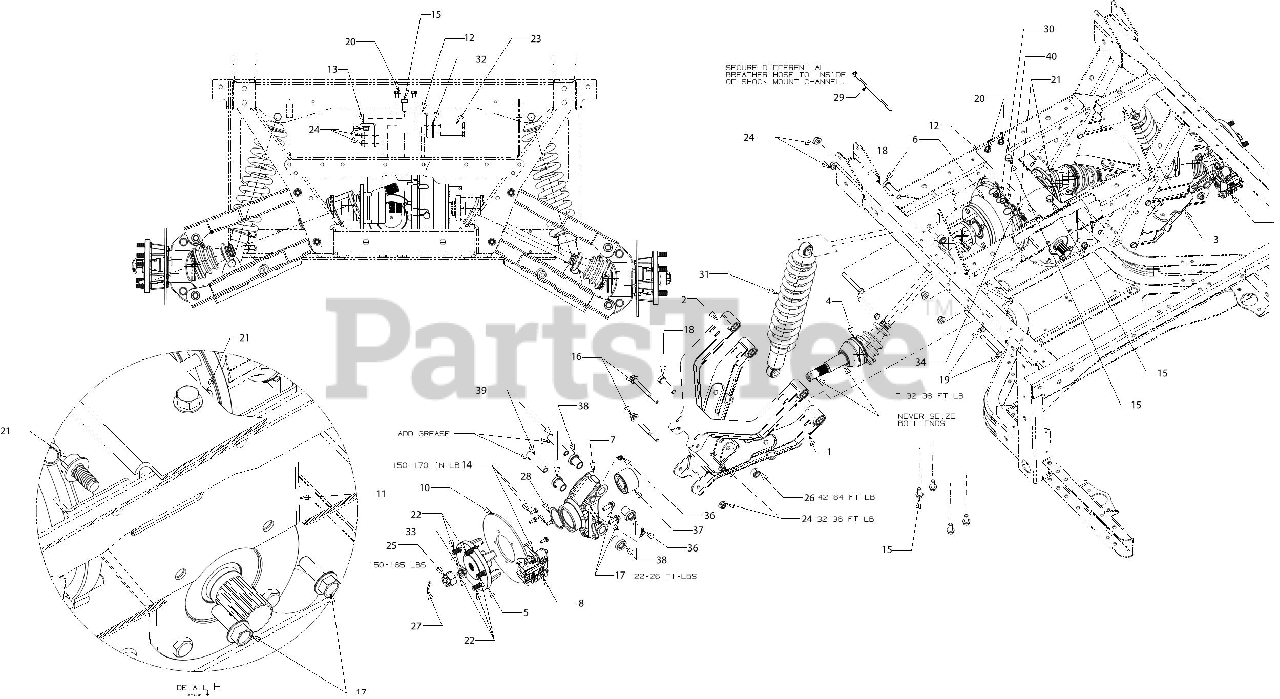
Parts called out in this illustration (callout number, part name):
1	LOWER CONTROL ASSEMBLY
2	UPPER CONTROL ASSEMBLY
3	LOWER CONTROL ASSEMBLY
4	CV JOINT AXLE:ASSEMBLY
5	WHEEL HUB ASSEMBLY
6	UV REAR DRIVE KIT
7	4X4 REAR HOUSING
8	FRONT BRAKE CALIPER ASSEMBLY (RH)
9	FRONT BRAKE CALIPER ASSEMBLY (LH)
10	BRAKE DISC 8.00 x .188
11	DIFFERENTIAL BRACKET
12	REAR DIFFERENTIAL MOUNT
13	REAR DIFFERENTIAL BRACKET
14	SCREW 1/4-20 x .62 SPEC GR5
15	SCREW 3/8-16 x .875 GR5
16	SCREW 3/8-16 x 4.00 GR5
17	SCREW M8 x 1.25 x 25MM GR8.8
18	SCREW 1/2-13 x 2 GR5
19	SCREW 3/8-16 x 3 GR8
20	SCREW 5/16-18 x .500
21	SCREW 3/8-16 x 3/4
22	STUD 7/16-14 x 1.6
23	SCREW 3/8-16 x 2.25 GR5
25	SLOTTED NUT22X1.5
26	HEX LOCK NUT NYLON
27	COTTER PIN-5/32 DIA
28	RETAINING RING
29	CABLE TIE
30	HOSE CLAMP
31	REAR SHOCK ABSORBER
32	FLAT WASHER .385X.870X.090
33	THRUST WASHER
36	45 DEGREE LUBE FITTING 1/4-28 TAPER
37	DOUBLE ROW BEARING
38	FLANGE BEARING .625 ID
40	FUEL HOSE LOW PERMEATION
